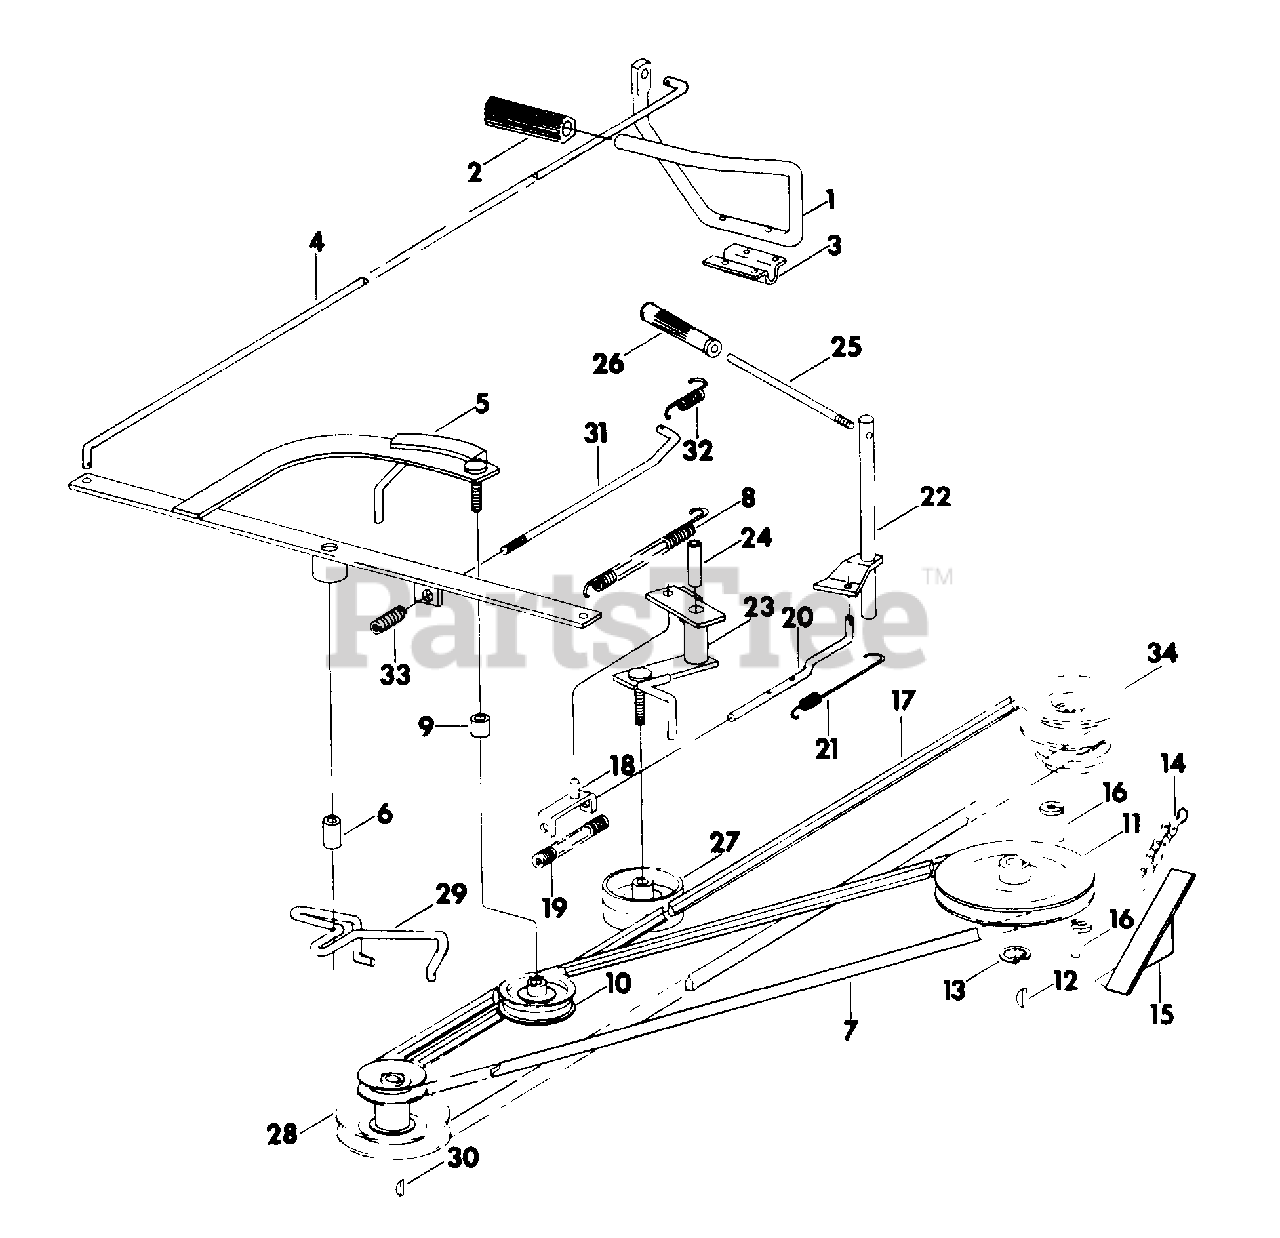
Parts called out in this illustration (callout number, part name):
1	PEDAL, CLUTCH AND BRAKE
3	CLAMP, PEDAL PIVOT
4	ROD, CLUTCH CONTROL
5	ARM ASSY, SHIFTER PIVOT
6	BUSHING, SHIFTER ARM
7	BELT, FORWARD DRIVE
8	SPRING, PEDAL RETURN
9	SPACER, 3/8 STD X .906 PIPE
10	IDLER, BALL BRG
11	PULLEY, TRANS DRIVE
12	KEY, 3/16 X 3/4 SAE 9 WOODRUFF
13	RING, RETAINING
14	CHAIN, FINAL REDUCTION
15	SHIELD ASSY, DRIVE CHAIN
16	GUIDE, BELT
17	BELT, MOWER DRIVE
18	STRAP ASSY, IPTO
19	SPRING, IPTO
20	ROD, MOWER SHIFTER
21	SPRING, IPTO RETURN
22	LEVER ASSY, SHIFTER
23	LEVER ASSY, SHIFTER ARM
24	BUSHING, IPTO 7 HP
25	ROD, SHIFTER HANDLE
26	GRIP, SHIFTER HANDLE
27	PULLEY, MOWER SHIFTER IDLER
28	PULLEY, ENG AND MOWER DRIVE
29	GUIDE, BELT PTO AND FORWARD DRIVE
30	KEY, 5/32 X 5/8 SAE 6 WOODRUFF
32	SPRING, BRAKE RETURN
33	SPRING, COMPRESSION
34	PULLEY, CENTER
